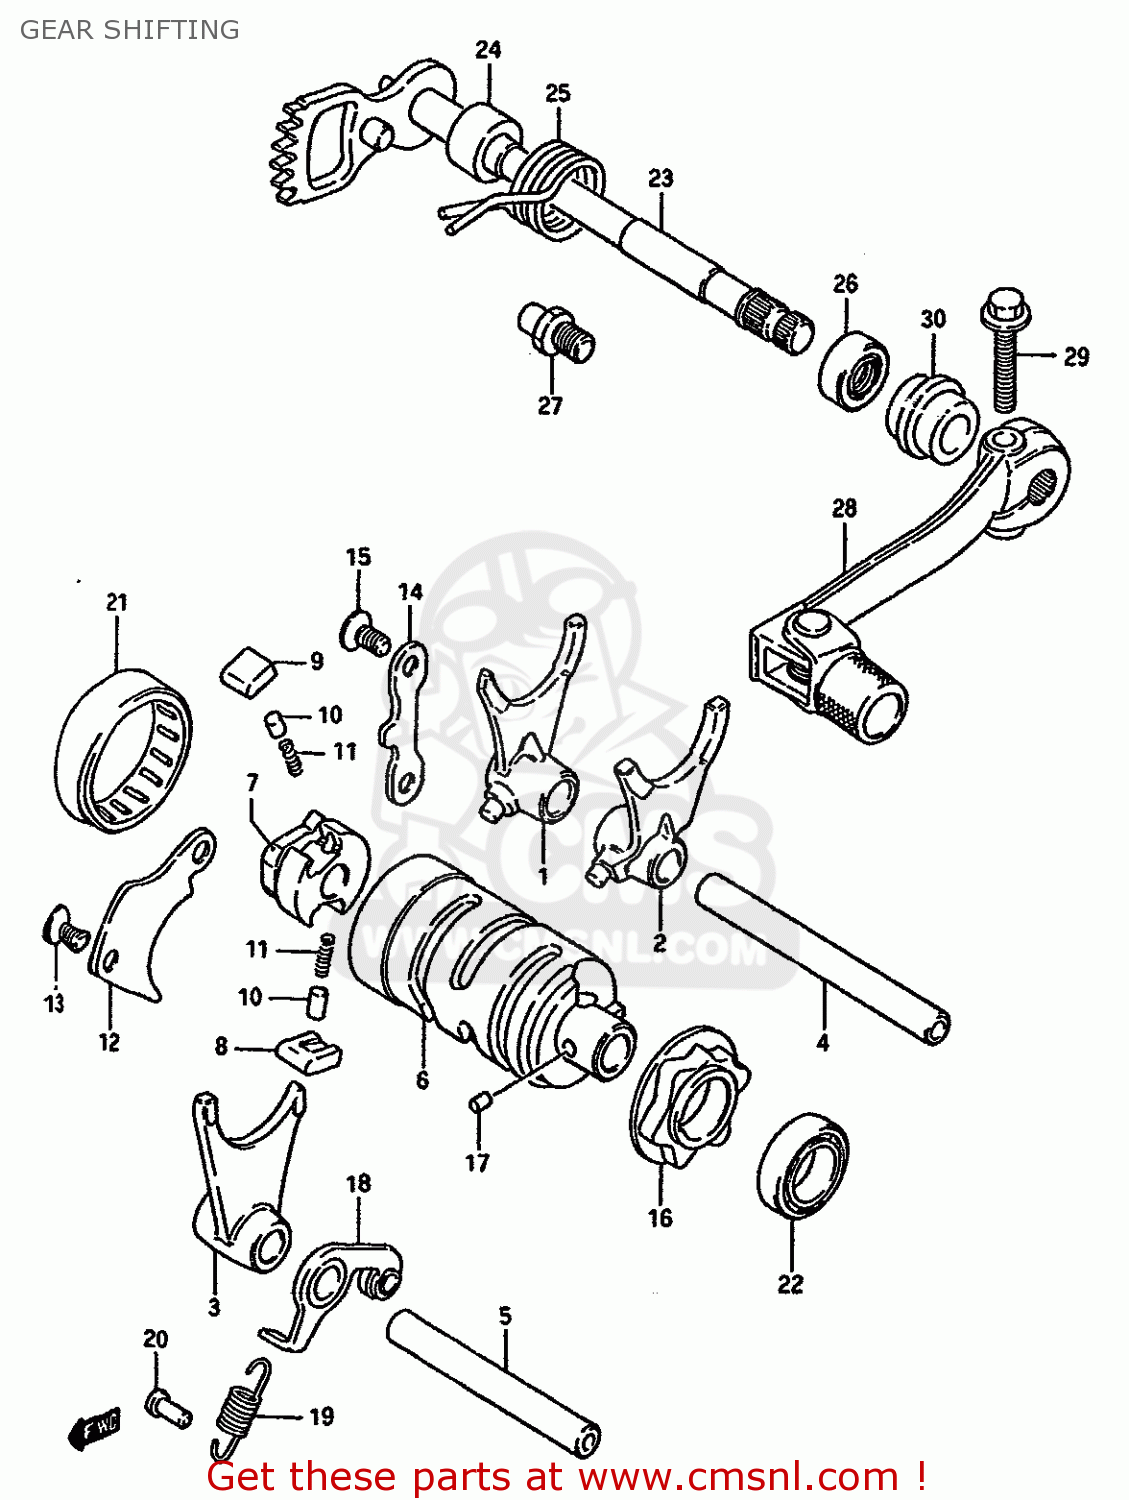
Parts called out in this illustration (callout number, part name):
1	FORK,GEAR SHIFT NO.1
2	FORK,GEAR SHIFT NO.2
3	FORK,GEAR SHIFT NO.3
4	SHAFT,GEAR SHIFT FORK
5	SHAFT,GEAR SHIFT FORK
6	CAM,GEAR SHIFT
7	GEAR,GEARSHIFT CAM DRIVE
8	PAWL,GEAR SHIFT NO.1
9	PAWL,GEAR SHIFT NO.2
10	PIN(5X8)
11	SPRING
12	LIFTER,GEAR SHIFT PAWL
13	SCREW
14	GUIDE,GEAR SHIFT CAM
15	SCREW
16	PLATE,GEAR SHIFT CAM STOPPER
17	PIN
18	STOPPER,GEAR SHIFTING
19	SPRING
20	RIVET
21	BEARING
22	BEARING
23	SHAFT COMP,GEAR SHIFTING
24	SPACER(12X20X15.3)
25	SPRING
26	OIL SEAL
27	STOPPER,GEAR SHIFT CAM
28	LEVER ASSY,GEAR SHIFT
29	BOLT
30	CUSHION
